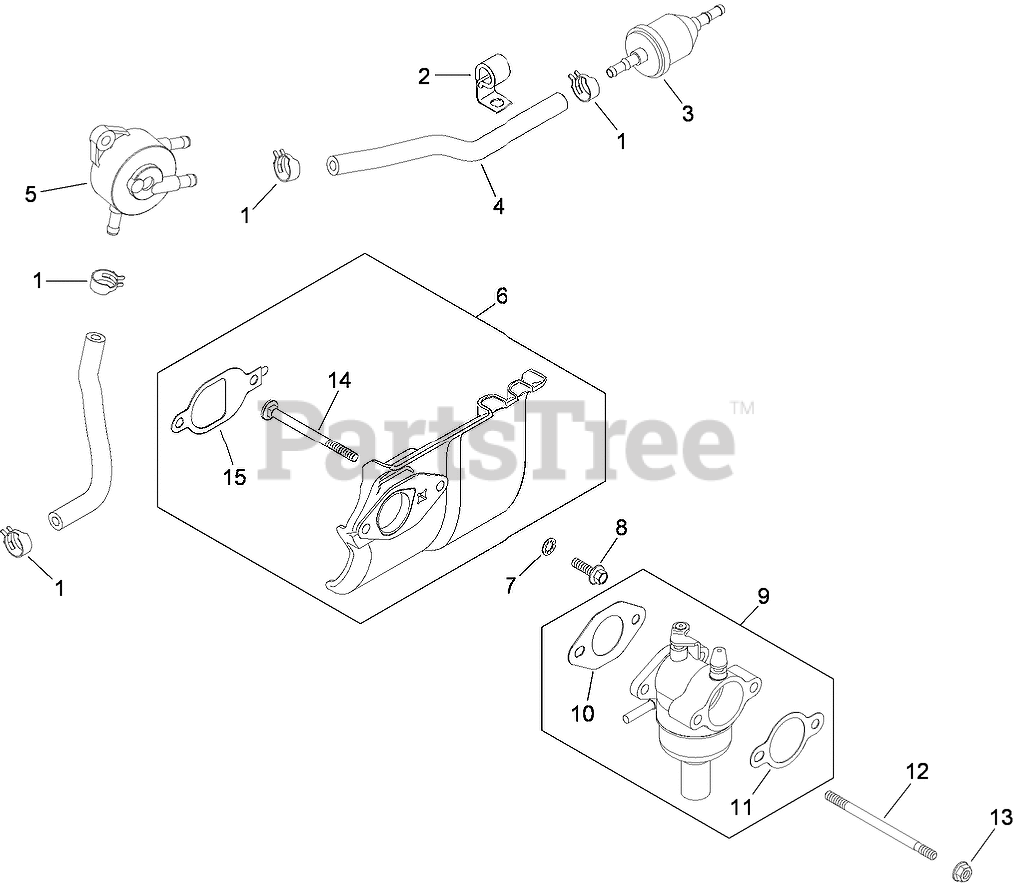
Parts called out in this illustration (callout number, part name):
1	CLAMP-HOSE, SPRING (1/2)
2	CLIP-CABLE
3	FILTER-FUEL
4	LINE-FUEL (24.0 CUT TO LENGTH)
5	PUMP-FUEL
6	HEAT DEFLECTOR KIT (INCLUDES REF 11, 14, 15, 20 332 01-S)
7	Washer-Lock, Internal Tooth (1/4)
8	Screw-Flange, Hex (M6x1.0x20)
9	CARBURETOR KIT (INCLUDES REF 10, 11) (S/W 12 755 109-S, 12 755 110-S, 12 757 02-S, 12 757 03-S, 12 757 33-S, 12 757 37-S, 20 755 07-S)
10	Gasket-Carburetor
11	Gasket-Base, Air Cleaner
12	Stud-Mounting, Carburetor (M6X1.0X100)
13	NUT-FLANGE (M6X1.0)
14	STUD-CARBURETOR
15	GASKET-DEFLECTOR, HEAT
